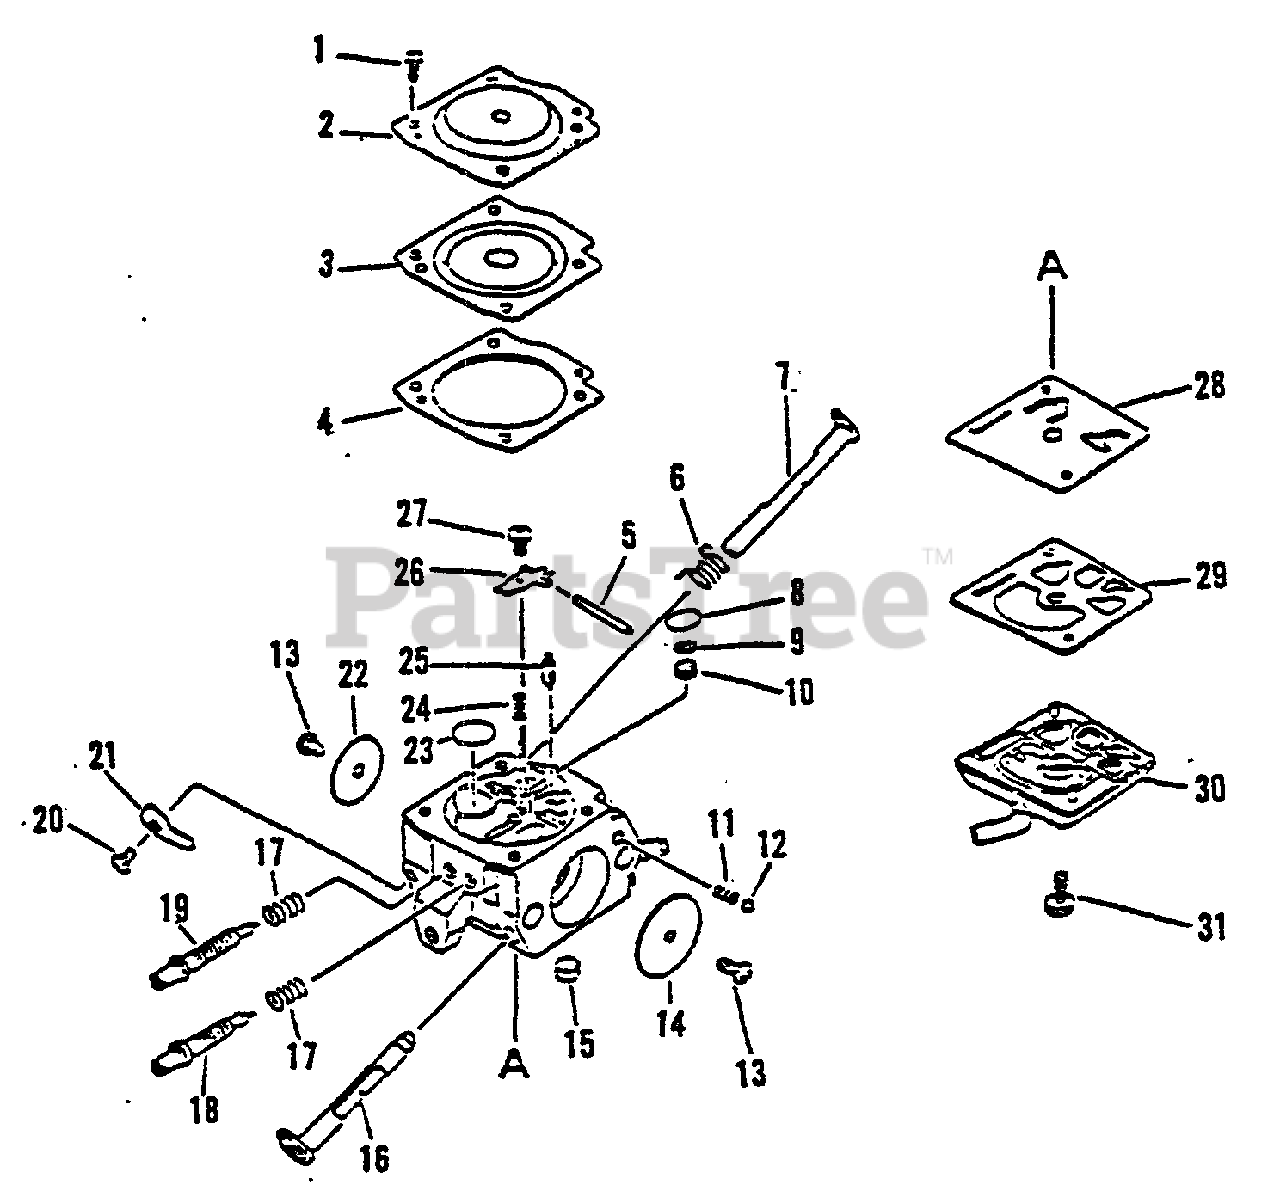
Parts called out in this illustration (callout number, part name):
1	SCREW
2	COVER, DIAPHRAGM
3	DIAPHRAGM
4	GASKET, DIAPHRAGM
5	PIN, METERING LEVER
6	SPRING, THROTTLE RETURN
7	SHAFT, THROTTLE
8	PLUG, WELCH
9	RING, RETAINING
10	STRAINER
11	SPRING, THROTTLE FRICTION
12	BALL, CHOKE
14	VALVE, CHOKE
16	SHAFT, CHOKE
17	SPRING
18	NEEDLE, HIGH SPEED
19	NEEDLE, IDLE
21	LEVER, THROTTLE
22	VALVE, THROTTLE
23	PLUG, WELCH
24	SPRING
25	VALVE, NEEDLE
26	LEVER, METERING
27	SCREW
28	DIAPHRAGM, PUMP
29	GASKET, PUMP
30	COVER, PUMP
